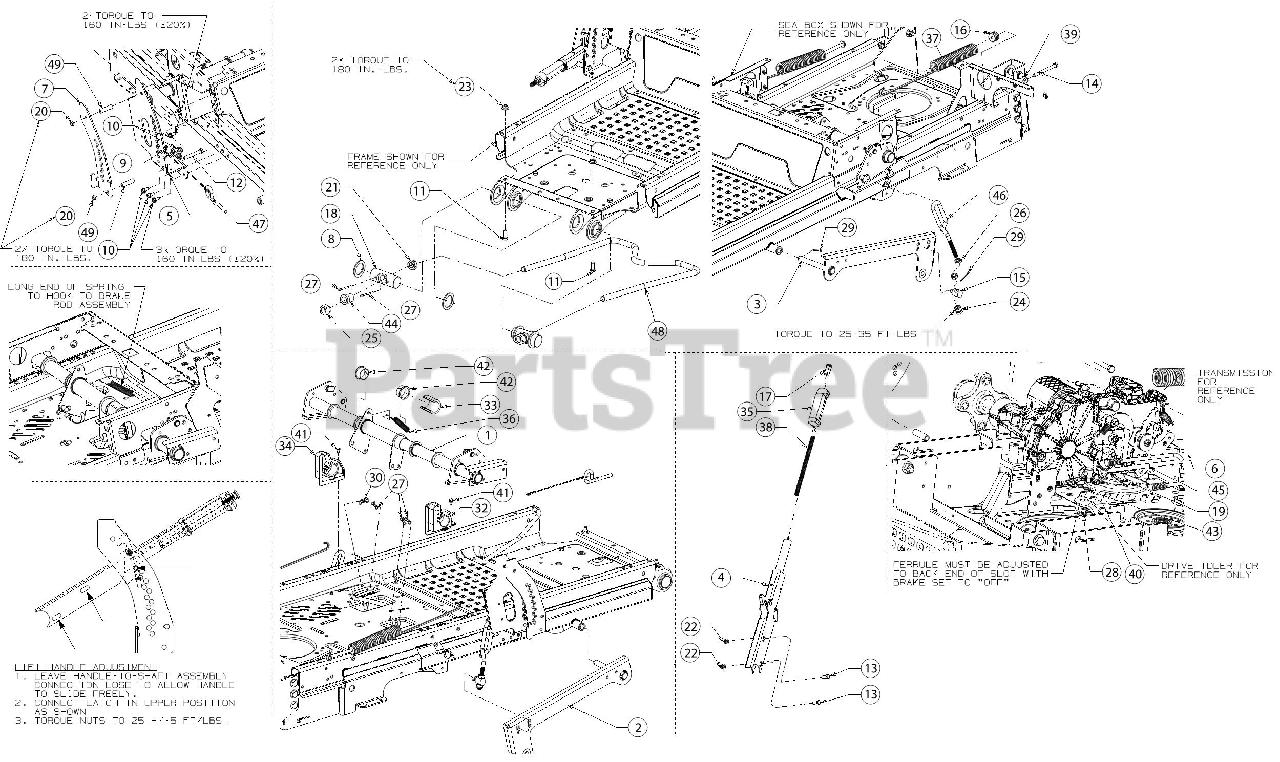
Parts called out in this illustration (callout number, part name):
1	DECK LIFT SHAFT ASSEMBLY
4	LATCH HANDLE ASSEMBLY
6	BRAKE ROD ASSEMBLY
7	OUTER INDEX BRACKET
8	FLAT SPACER
9	HEX SCREW AB-TAP #10-16 x 0.500
10	SCREW 5/16-18 x .750
11	SCREW 3/8-16 x 1 GR5
12	HEX SCREW-3/8-16X2.5 GR5
13	SCREW 5/16-18 x .75 GR5
14	SCREW 3/8-16X4.25 GR5
15	LIFT LINK FERRULE
16	SPRING INSERT
17	LIFT HANDLE BUTTON
18	PIVOT LIFT PIN
19	FERRULE 3/8-24 x .375
20	JAM LOCK NUT
21	HEX JAM NUT 3/4-10
22	FLANGE LOCK NUT 5/16-18
23	FLANGE LOCK NUT
24	HEX NUT NYLOK 1/2-13
25	NYLOCK NUT 3/4-10
26	HEX NUT
27	COTTER PIN
28	BOW TIE COTTER PIN 1/4-5/16
29	COTTER PIN
30	BOW TIE COTTER PIN
32	DECK LIFT BRACKET
33	SPACER-1.375 SHAFT
34	DECK LIFT BRACKET (LH)
35	LIFT HANDLE GRIP
36	EXTENSION SPRING .63 x 4.95
37	EXTENSION SPRING 1.485 OD x 17.58
38	COMPRESSION SPRING
39	FLAT WASHER .385X.870X.090
40	WASHER THRUST .375X.70X.030
41	SHOULDER SCREW 1/4-20X.50 19"PSH
42	FLANGE BEARING
43	FLANGE BEARING
44	FLANGE BEARING
45	DISENGAGEMENT BRAKE ROD
46	LIFT ADJUSTMENT LINK
48	DECK HANGER ROD
